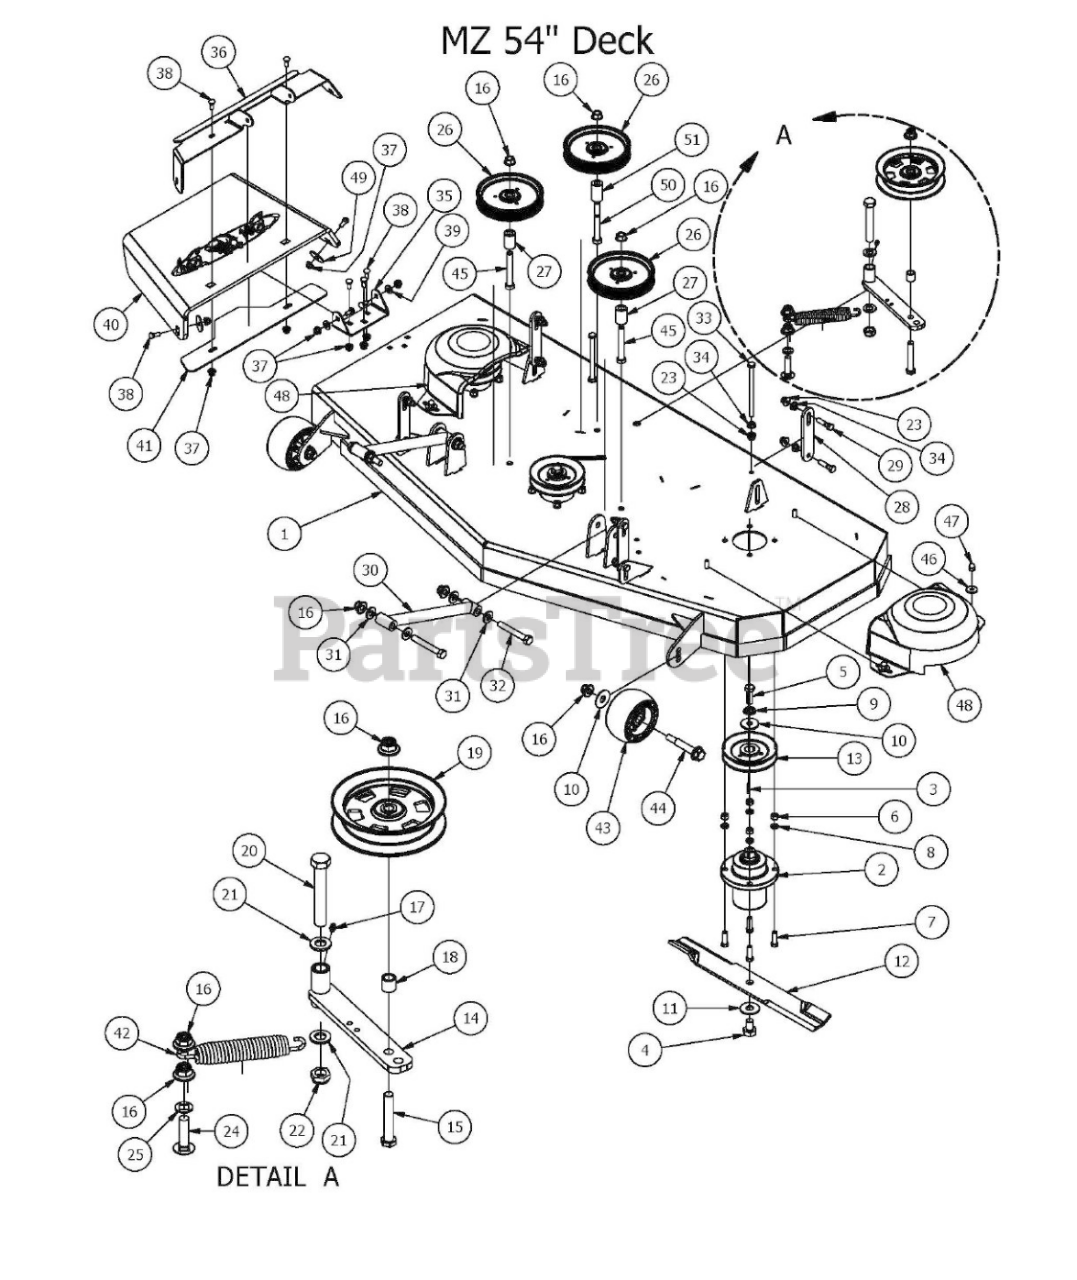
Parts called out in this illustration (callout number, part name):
1	2017 MZ 54" Deck
3	3/16 x 1 Square Key
4	5/8" x 1 1/2" Grade 8 Hex Bolt (Fine)
5	1/2"-20 x 1 1/2 - Grade 5 Fine Thread Bolt
6	3/8" Hex Nut
7	3/8" x 1 1/4" Hex Bolt
8	3/8" Lock Washer
9	1/2" Lock Washer Zinc
10	1/2" Belleville Washer
11	5/8" Flat Washer
12	54" MZ Fusion Blade
13	54 MZ Spindle Pulley
14	Deck Idler
15	1/2-13 x GR 5 Hex Bolt Zinc
16	1/2-13 Nylon Insert Flange Nut
17	1/4" Press in Grease Fitting
18	Spacer 3/4 OD x 1/2 ID x 3\4 Length
19	5" Idler Pully
20	5/8" x 4" Hex Bolt
21	.630 ID Plastic Washer
22	5/8-11 Nylon Insert Jam Half Nut
23	3/8 Nylock Flange Nut
24	1/2 x 2" Carriage Bolt
25	.517 Square Hole Round Washer
26	5-3/4 Idler Pulley-Capitol Stampings
27	Idler Pulley Standoff
28	2017 MZ/ZT Deck Hanger
29	3/8" x 1 1/2" Hex Bolt
30	MZ/ZT Deck Locator
31	.505 Nylon Spacer
32	1/2-13 x 3 1/2 GR 5 Hex Bolt
33	3/8-16 x 5 1/2 Hex Bolt
34	3/8" Flange Nut
35	Chute Hanger 48 MZ
36	Discharge Chute Bracket 48 MZ (Upper)
37	5/16" Nylon Flange Nut
38	5/16-18x3/4 carriage bolt
39	.360 ID Plastic Washer
40	Rubber Discharge Chute MZ (Component)
41	2017 MZ Discharge Chute Bracket-Lower
42	2015 Deck Idler Spring
43	Deck Wheel
44	Deck Wheel Bolt
45	1/2 x 3 1/2 Flange Bolt Grade 8
46	.360 ID Plastic Washer-Black
47	Acorn nut-pulley Cover
48	Pulley Cover
49	5/16" Fender Washer
50	1/2" x 4" Bolt (Grade 8)
51	13/4" Pulley Spacer
